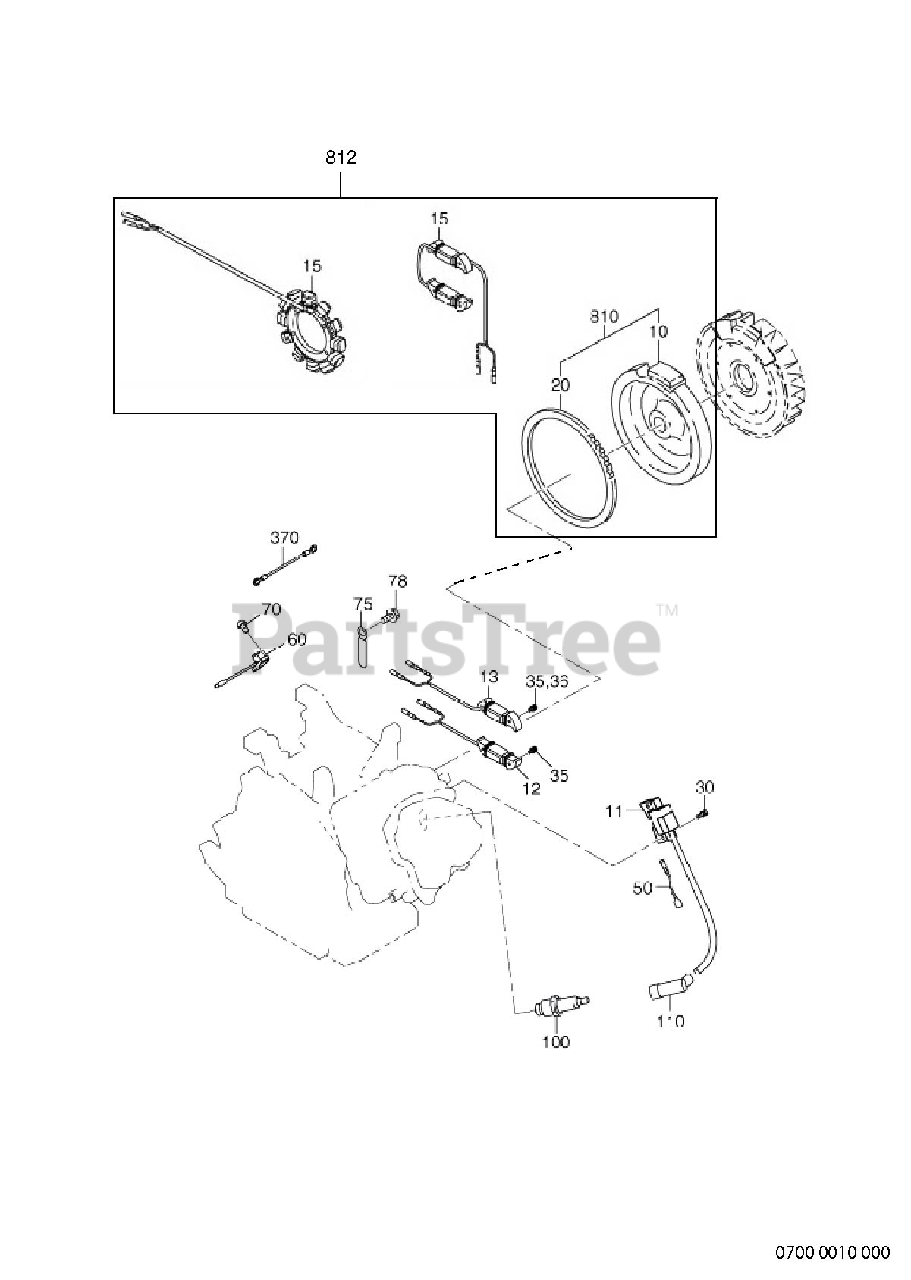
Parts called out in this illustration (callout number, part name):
10	FLYWHEEL CP
11	IGNITION COIL CP
12	CHARGE COIL CP
30	BOLT AND WASHER
35	SCREW AND WASHER
100	SPARK PLUG
110	SPARK PLUG CAP
812	FLYWHEEL CP
